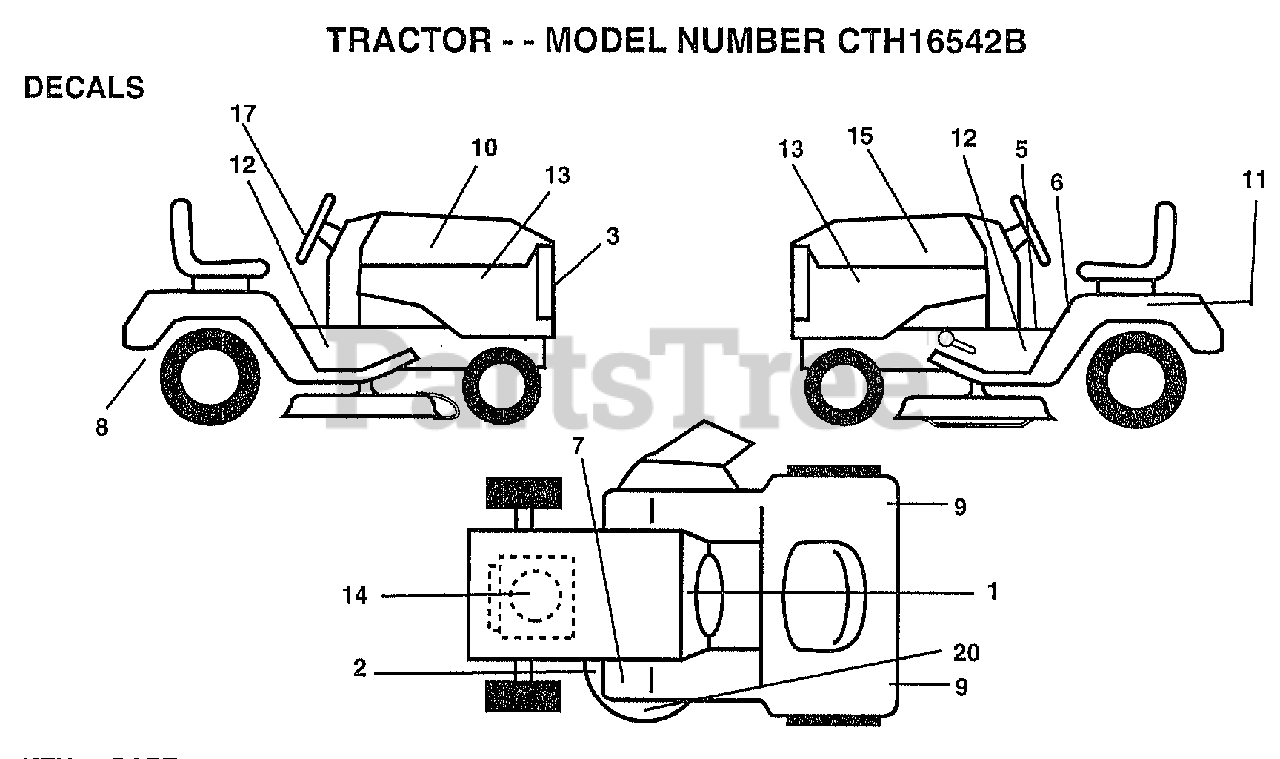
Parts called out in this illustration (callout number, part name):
1	"DECAL-INST,OPER"
2	"DECAL-SCHEM,BELT"
3	DECAL GRILLE
5	DECAL BRAK PARK
6	"DECAL DANGER,FEND"
8	DECAL DRAWBAR LH
9	REFLECTOR-TAIL YT
10	DECAL.HOOD.RH
11	DECAL.BATRY.3-3908
12	"DECAL CHASSIS 42"""
13	DECAL SIDE PANEL
14	DECAL ENGINE
15	DECAL.HOOD.LH
17	DECAL INST STG WH
20	"DECAL,ENVIRO DECK"
